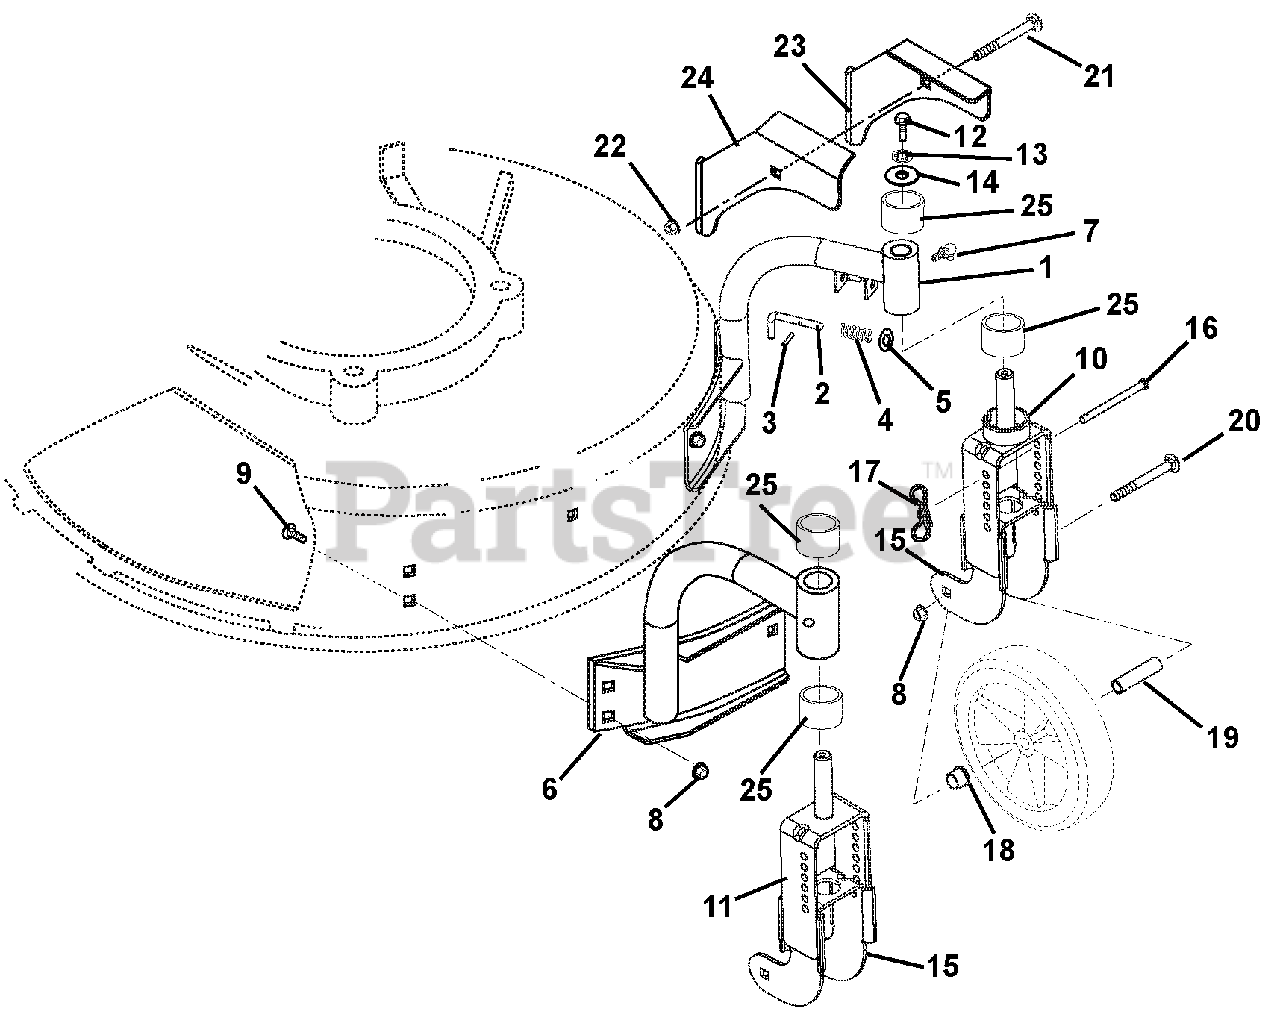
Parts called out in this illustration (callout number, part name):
1	WELDMENT, LH MOUNT
2	PIN, LOCKOUT
3	PIN-ROLL .093X.50
4	SPRG, COMP--SWVL LOCKOUT
5	@WSHR-FL-STL.281X.62X.065 YWZC
6	WELDMENT, RH MOUNT
7	FTG-LUBE .25-28X.256 YWZC
8	@NUT-LK-TOP-FLG .31-18 YWZC
9	@BLT-RDHDSQNK .31-18X.50 G5YZ
10	YOKE, OUTER LH
11	YOKE, RH OUTER
12	@BLT-HEX .25-20X.75 GR5 YWZC
13	WSHR-LK .250X.077 HVY YWZC
14	WSHR-FL-STL .281X1.000X.063
15	YOKE-INNER
16	PIN, HEIGHT ADJUSTMENT
17	PIN, BOW TIE LOCKING COTTER
18	BSHG-FLG .500X.625X.500X.750
19	SPCR, WHEEL .385X.500X2.00
20	BLT-RDHDSQSHNK.31-18X2.75G2YWZ
21	@BLT-RDHDSQNK .25-20X1.50 G5YZ
22	@NUT-SPNLK-FLG .25-20 YWZC
23	BRACKET, HOOD CABLE--LH
24	BRACKET, HOOD CABLE WELDMENT
25	BSHG-SLV .625X.750X.500 BR
26	@WSHR-FL-STL.250X.56X.049 YWZC
27	@PIN-CTR .09X.50 EXTPRSQCT YWZ
